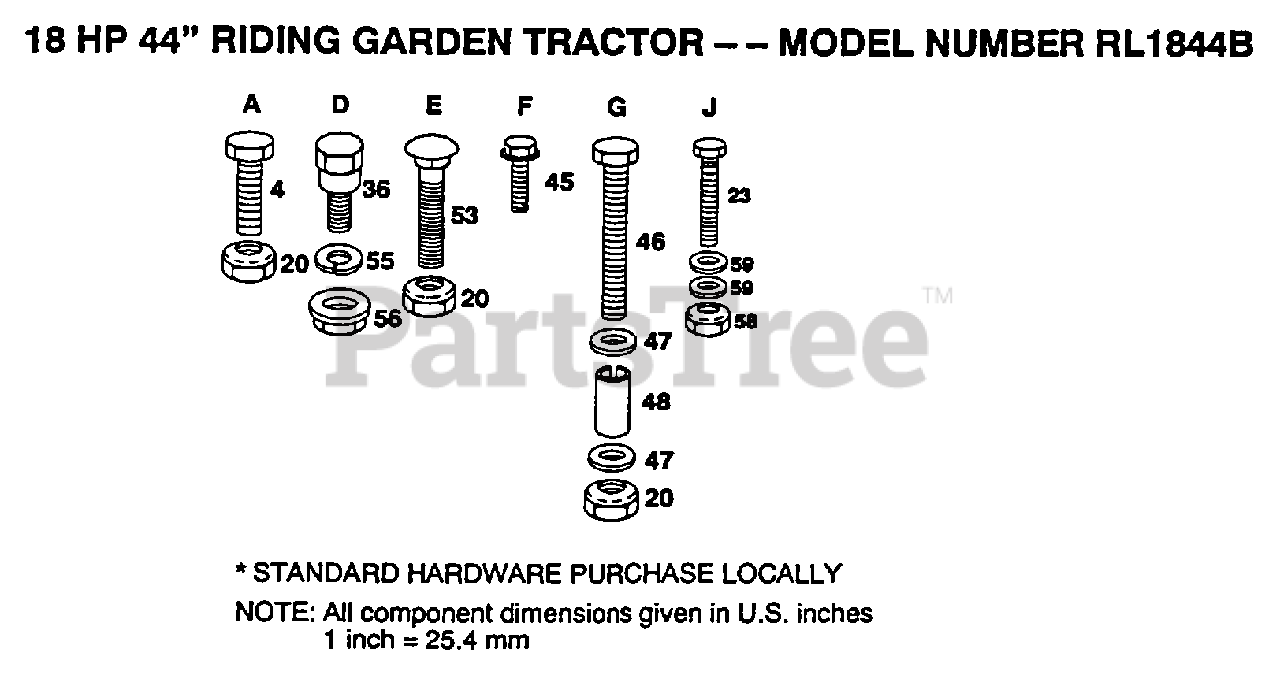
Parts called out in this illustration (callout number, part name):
23	BOLT LT
36	"BOLT, SHOULDER LT"
45	SCREW
55	WASHER T
56	NUT SPECIAL T
59	WASHER
